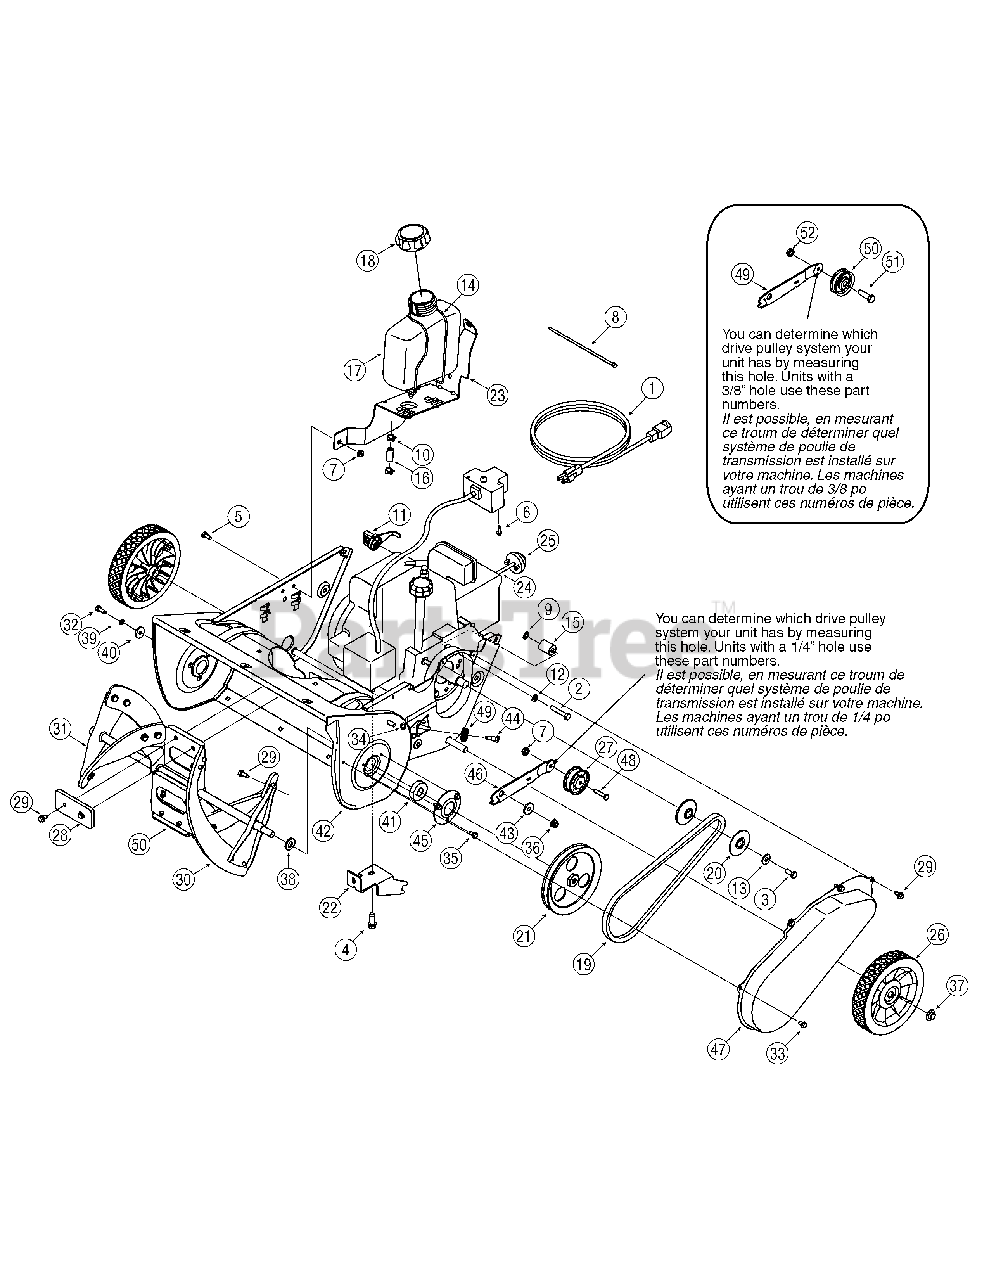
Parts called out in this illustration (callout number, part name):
1	Extension Cord 10 Ft.
2	Hex Bolt 5/16-24 x 1.75
3	Hex L-Bolt 5/16-24 x .75 Gr. 5
4	Hex Wash HD Tap Scr 3/8-16 x .88
5	Hex Bolt 1/4-20 x .62 Gr. 5
6	Hex Wash B-Tapp Scr #10 x .62" Lg.
7	Hex L-Flanged Nut 1/4-20 Gr. F Nylon
8	Push Mount Tie
9	Push Speed Nut
10	Hose Clamp
11	Choke Knob
12	L-Wash 5/16 ID
13	Flat Washer .349 ID x .879 OD x .063
14	Gas Tank Wire Support
15	Spacer .875 x .320 x 1.10
16	Fuel Line
17	Fuel Tank 2 Quart
18	Cap-Fuel
19	V-Belt 1/2 x 35.0" Lg.
20	Pulley Half .625 ID x 2.25 OD
21	1/2" V-Pulley 1/2-20 LH x 6,0" OD
25	Primer
26	Wheel-Star, 7.5 x 1.5 Yellow
27	Idler Pulley (1/4" hole)
28	Rubber Paddle
29	Hex B-Tap Scr 1/4-28 x .25" Lg
30	Rubber Spiral-Crescent
32	Thd Form ing Scr. 1/4-20 x .75 Lg.
33	Hex Wash HD Tapp Scr 1/4-20 x .375
34	Hex Ins Jam L-Nut 1/4-28
35	Hex Tap Scr. 1/4-20 x .50" LG.
36	Flange Locknut 5/16-18 Gr. F, Nylon
37	Push Cap x 1/2" Rod
38	Flat Washer .50 ID x 1.00 OD x .125
39	L-Wash 1/4 ID
40	Flat Washer .25 ID x .93 OD x .125
41	Ball Bearing 17 x 40 x 12
43	Shoulder Spacer .25 THK
44	Hex Shld.Scr.1/4-28 x .375
48	Hex Screw 1/4-20 x 1.25 Gr. 5 Special
49	Cable Guide Roller
50	Auger Assembly
51	Idler Pulley w/brake ( Pulley hole 3/8")
52	Idler Pulley (3/8" hole)
53	Hex Screw 3/8-24 x 1.25
54	Jam Locknut 3/8-24
